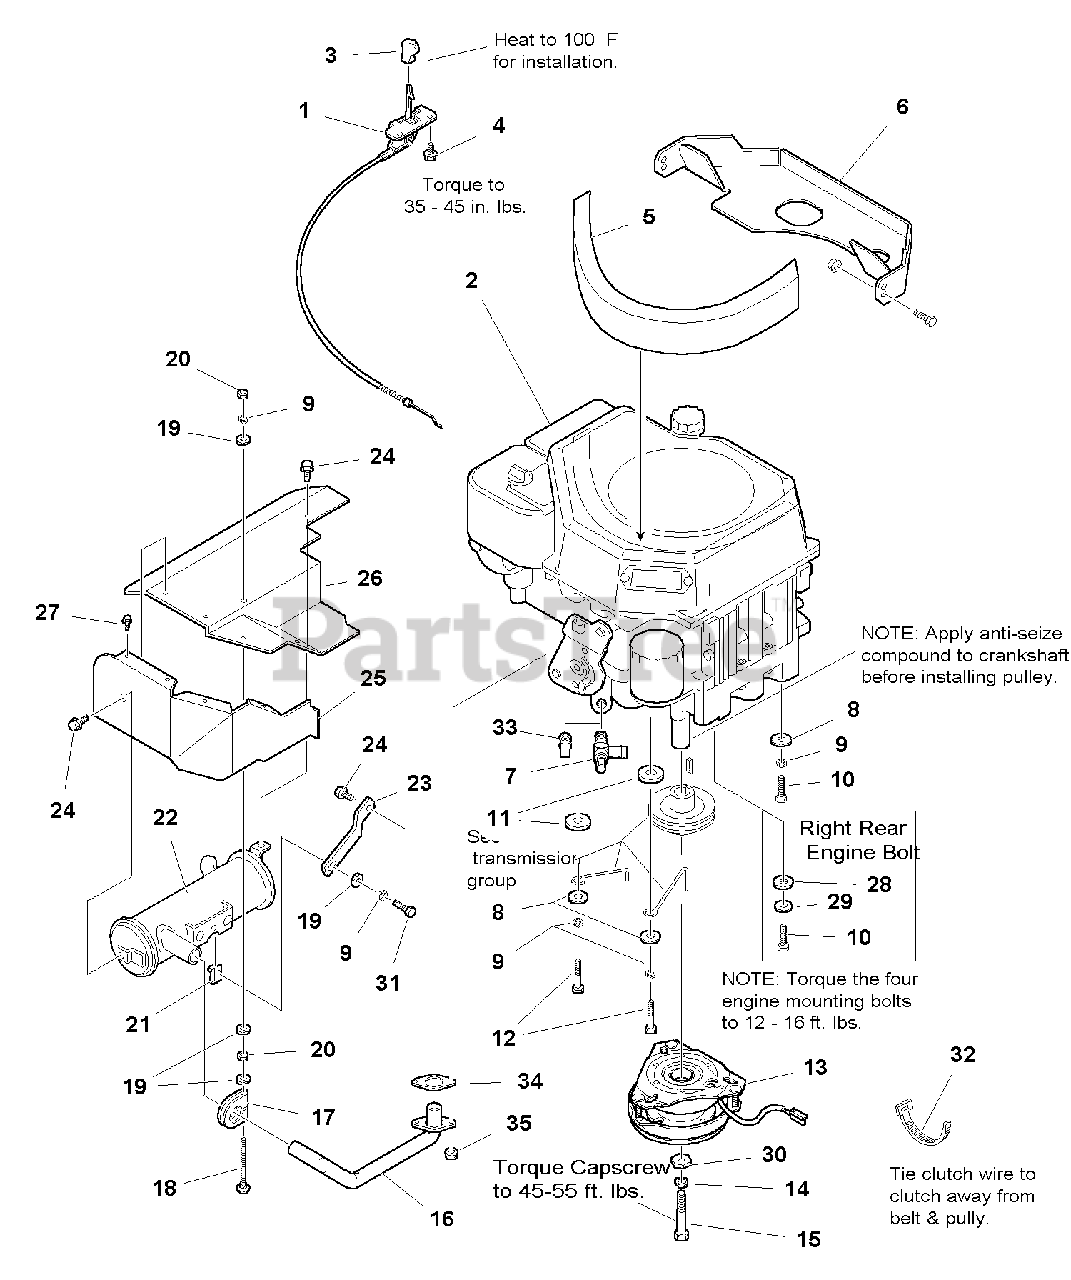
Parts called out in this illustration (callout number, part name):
1	THROTTLE CONTROL ASSEMBLY
3	KNOB, Throttle
4	CAPSCREW, Plastite, 1/4-10 x 1/2
5	SEAL, Air Inlet
7	VALVE, Shut Off
8	WASHER, Plain, 5/16
9	LOCKWASHER, 5/16
10	CAPSCREW, Hex, M08 - 1.25 x 30mm
11	WASHER, Plain
12	CAPSCREW, Hex Head, M08 - 1.25 x 40mm
13	CLUTCH, Electric
14	LOCKWASHER, 7/16
15	CAPSCREW, Hex, 7/16-20 x 3
16	PIPE, Exhaust
17	CLAMP, Muffler
18	CARRIAGE BOLT, 5/16-18 x 3-1/4
19	WASHER, 5/16
20	NUT, Hex, 5/16-18
21	NUT, Speed, 5/16-18
22	MUFFLER ASSEMBLY
23	SUPPORT, Muffler
24	CAPSCREW, Hex, Taptite, 5/16-18 x 1/2
25	AIR DUCT, Bottom
26	SHIELD, Muffler
27	CAPSCREW, Hex, Thd. Form, #10-16 x 3/8
28	WASHER, Plain, 5/16
29	LOCKWASHER, Internal Tooth, 5/16
30	WASHER, Hex
31	CAPSCREW, Hex Head, 5/16-18 x 1
32	TIE, Self Locking
33	PLUG, Fuel
34	GASKET, Muffler
35	NUT, Hex Flange
